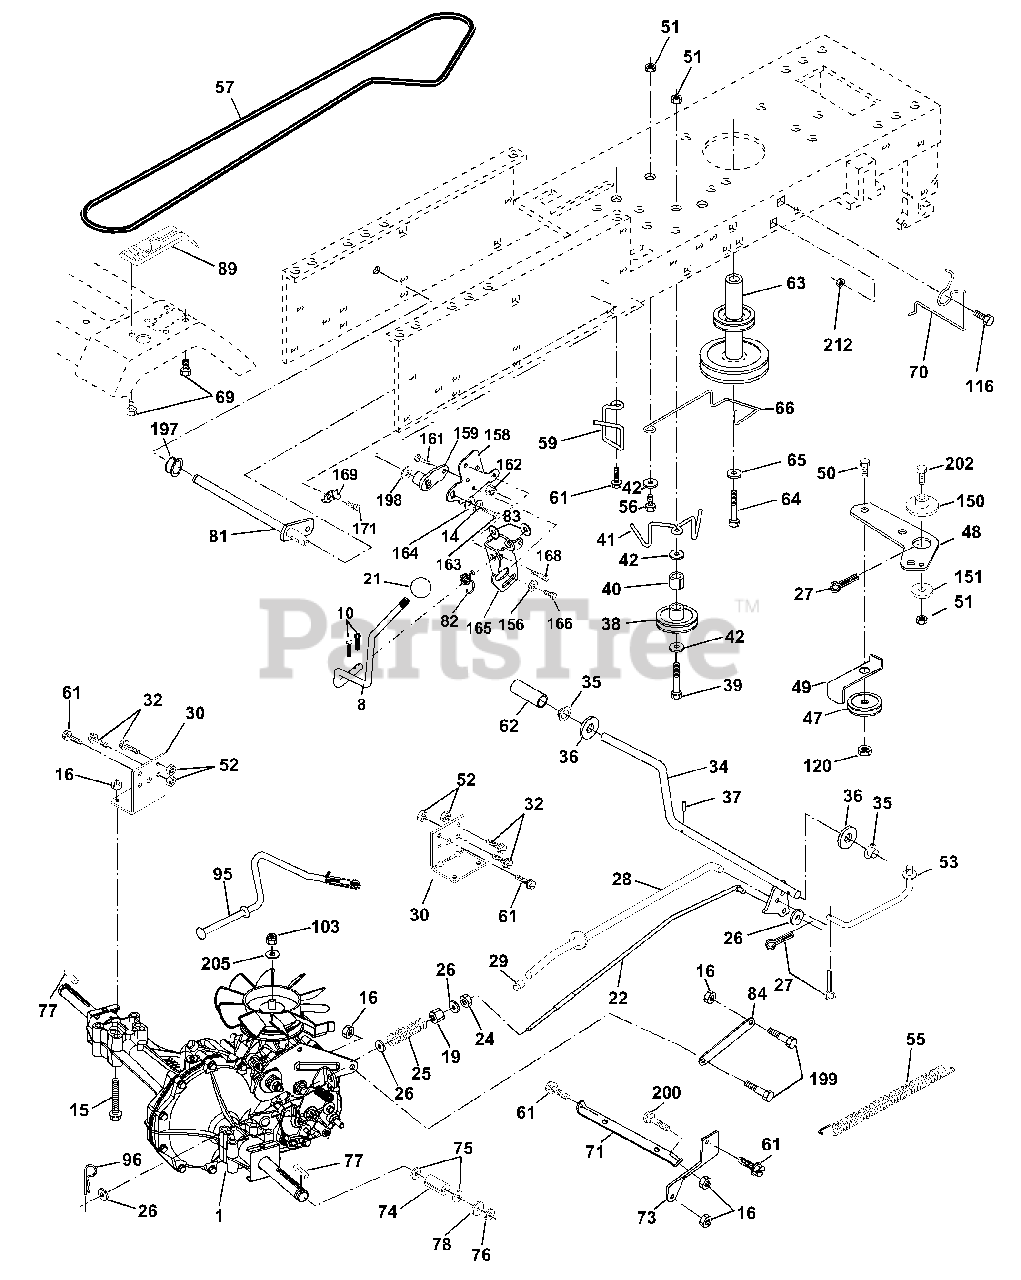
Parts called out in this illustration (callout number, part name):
10	Pin, Cotter 1/8 x 1
14	Washer Lock 1/4
15	Bolt Hex Flghd 5/16-18 Gr. 5
16	Nut, Lock Hex w/Ins 5/16-18 UNC
19	Nut, Lock Hex w/Wsh 3/8-16 UNC
21	Knob Rd. 1/2-13 Plstc. Thds. Blk.
22	Rod, Brake
24	Nut
25	Spring, Rod, Brake
26	Washer 13/32 x 13/16 x 16 Ga.
27	Pin, Cotter 1/8 x 3/4
28	Rod, Parking Brake
29	Cap, Parking Brake
30	Bracket, Transmission
32	Bolt Hex 5/16-18 UNC x 3/4
34	Shaft, Foot Pedal
35	Bearing, Nylon
36	Washer
37	Pin, Roll
38	Pulley, Idler, Flat
39	Bolt
40	Spacer, Split
41	Keeper, Belt, Idler
42	Washer 13/32 x 13/16 x 12 Ga.
47	Pulley, Idler, V-Belt
48	Bellcrank Clutch Grnd Drustl
49	Retainer, Belt
50	Bolt
51	Nut
52	Nut Crownlock 5/16-28
53	Link, Clutch
55	Spring, Return, Clutch
56	Bolt, Hex 3/8-16 UNC x 1-1/4
57	V-Belt, Drive
59	Keeper, Belt, Center
61	Screw, 3/8-16 x 3/4
62	Cover, Pedal
63	Pulley, Engine
64	Bolt Hex 7/16 x 4 Gr. 5
65	Washer
66	Keeper, Belt Engine Hydro
69	Screw Hex Wsh Hi-Lo 1/4-1/2 Unc
70	Guide, Belt, Mower Drive RH
71	Strap, Torque, Lh
72	Washer 13/32 x 1-1/4 x 12 Ga.
73	Strap, Torque, Rh
74	Spacer, Axle
75	Washer 25/32 x 1-1/4 x 16 Ga.
76	Ring, E
77	Key, Square
78	Washer 25/32 x 1-5/8 x 16 Ga.
81	Shaft Asm Cross
82	Spring, Torsion
83	Washer 17/32 x 3/4 x 16 Ga.
84	Link Transaxle
89	Console, Shift
95	Control Asm Bypass Hydro
96	Spring, Retainer 1"
103	Nut, Hex Jam Toplock 1/2-20 UNF
116	Bolt Rdhd Sq Neck 3/8-16 x 1-1/4
150	Bushing Bellcrank Grd Drive
151	Washer 13/32 x 2 x 10
156	Washer 5/16 x 1.0 x 1.25
158	Bracket Shift Mount
159	Hub Tapered Flange Shift
161	Bolt Rdhd Sqnk 1/4-20 x 3/4 Gr. 5
162	Nut Crownlock 1/4-20 Unc
163	Bolt Hex Fin 1/4-20 x 1
164	Washer 5/8 x .281 x 10 Ga.
165	Bracket Pivot Lever
166	Screw 5/16 x 1.0 x .125
168	Bolt Shoulder 5/16-18 x .561
169	Plate Fastening LT
197	Nyliner Snap-in 5/8" ID
198	Washer Nyl 7/8 ID x .105" HYD
199	Bolt Shoulder 5/16-18 Unc
200	Bolt Rdhd Sqnk 5/16-18 Unc x 1
202	Bolt Car SH 3/8-16 x 1-1/2 Gr 5
205	Washer 17/32 x 1 x 16 Ga
